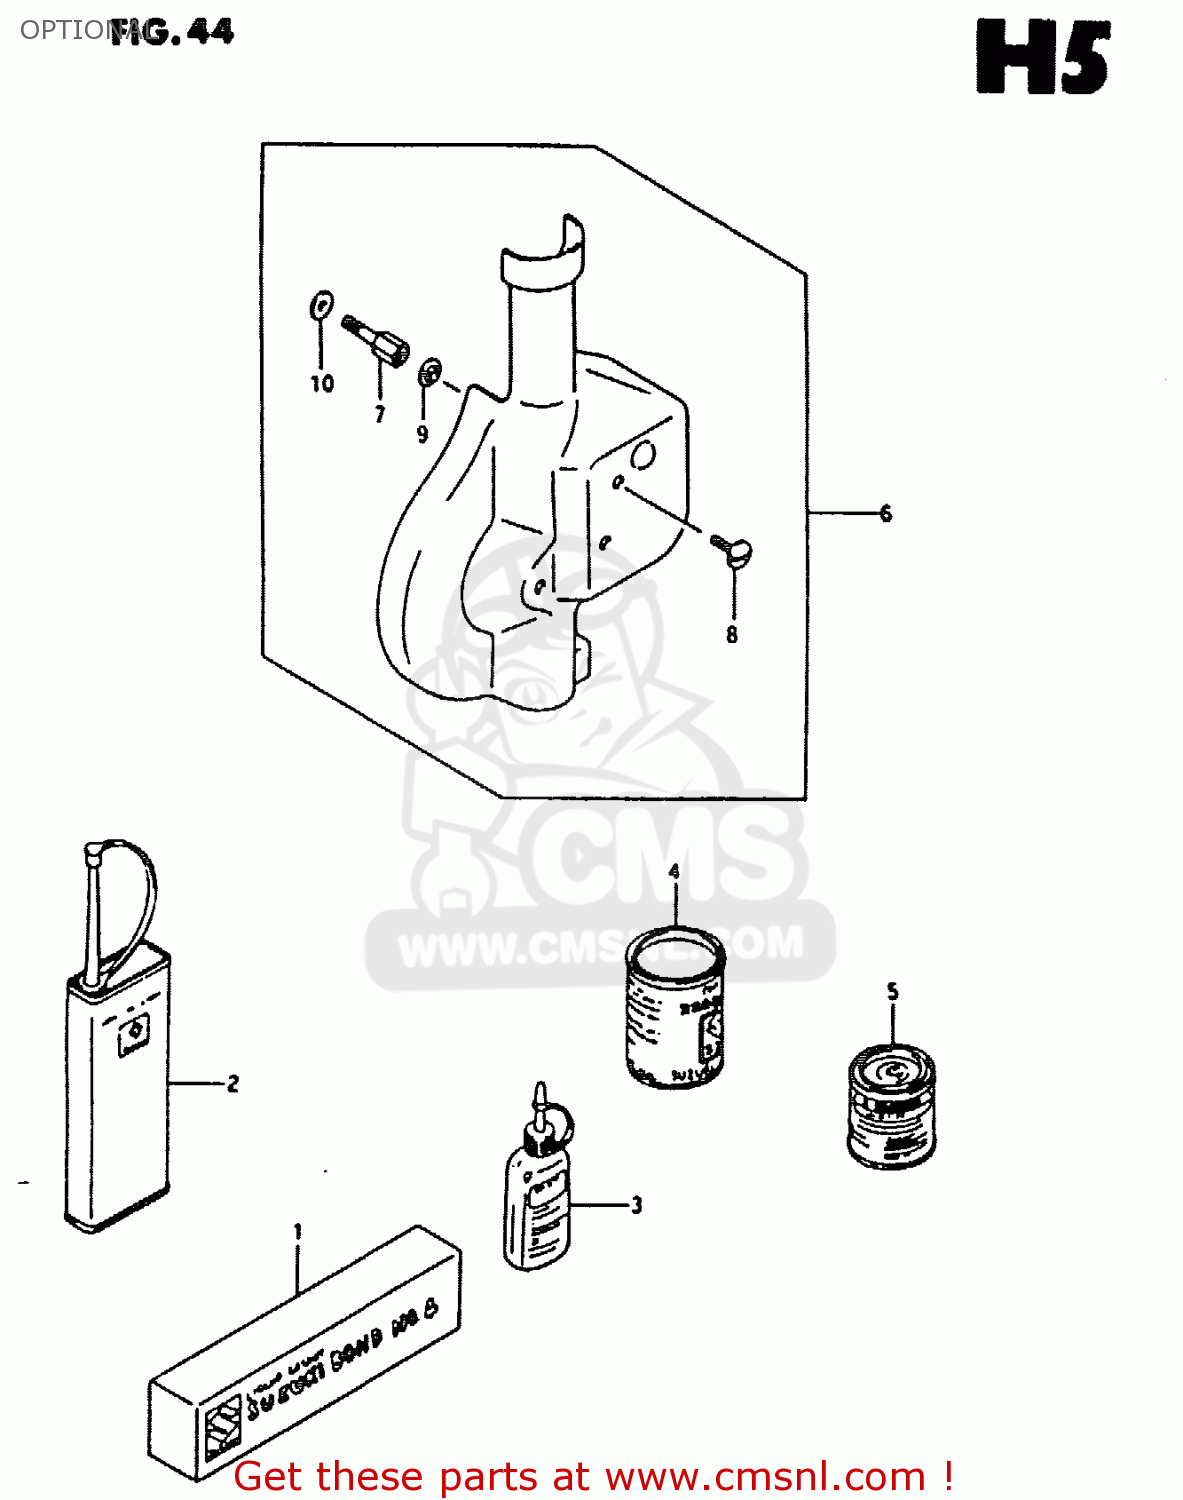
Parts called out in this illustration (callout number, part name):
1	BOND 1104
2	THREAD LOCK NO.1401 CLEAR 200G
3	THREAD LOCK NO
4	GREASE(C)EP2 LITHIUM 150G
5	PAINT,BLACK
6	COVER SET,FRONT DISC
7	BOLT,FRONT DISC COVER
8	SCREW(6X14)
9	WASHER
10	WASHER
